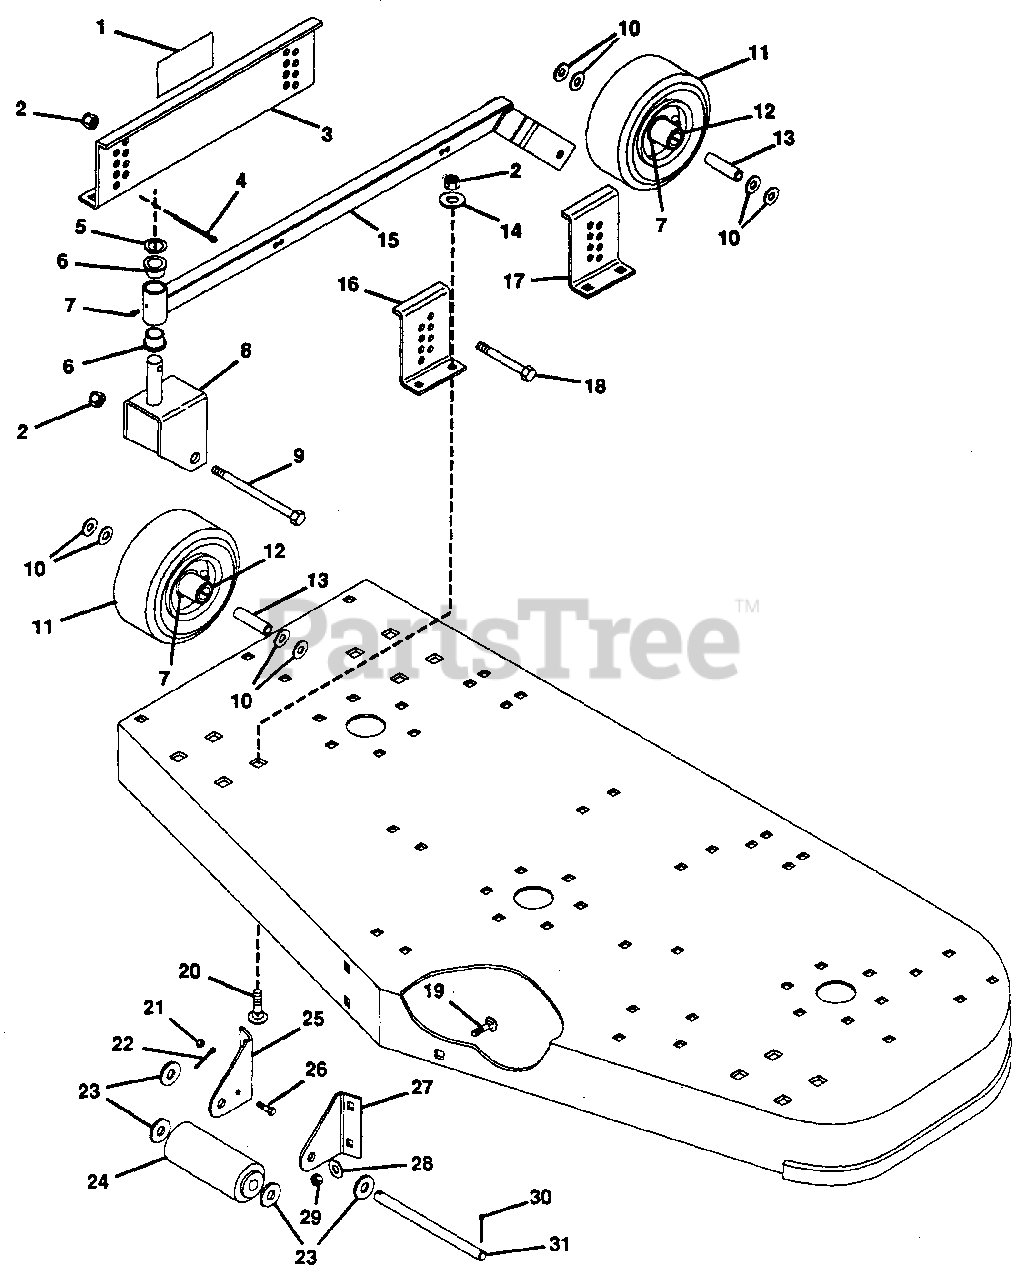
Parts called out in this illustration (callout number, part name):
1	Decal, Danger Foot
2	Nut, Lock 1/2-13
3	Bracket, Mower Support
4	Pin, Cotter .187x1.625
5	Race, Bearing Thrust
6	Bushing, Pivot
7	Fitting, Lube 1/4-28
8	Weldment, Caster Fork
9	Bolt, Hex 1/2-13x5.50
10	Washer, Flat .531x1.250x.100
11	Wheel, Gauge
12	Bearing, Ball
13	Bushing, Wheel
14	Washer, Flat .531x1.062x.095
15	Weldment, Caster Wheel Support
16	Bracket, Mwr Support RH(Front)
16	Bracket, Mwr Support LH(Front)
17	Bracket, Mwr Support RH(Rear)
17	Bracket, Mwr Support LH(Rear)
18	Bolt, Hex 1/2-13x3.00
19	Bolt, 3/8-16x1.00 Rd Hd Sq Nk
20	Bolt, Carriage 1/2-13x1.25
21	Nut, Hex 1/4-20
22	Pin, Cotter .250x2.00
23	Washer, Flat .656x1.312x.095
24	Roller, Gauge
25	Bracket, Roller R.H.
26	Bolt, Hex 1/4-20x.75
27	Bracket, Roller L.H.
28	Washer, Flat .406x.812x.065
29	Nut, Lock 3/8-16
30	Pin, Cotter .25x1.00
31	Shaft, Center Roller
